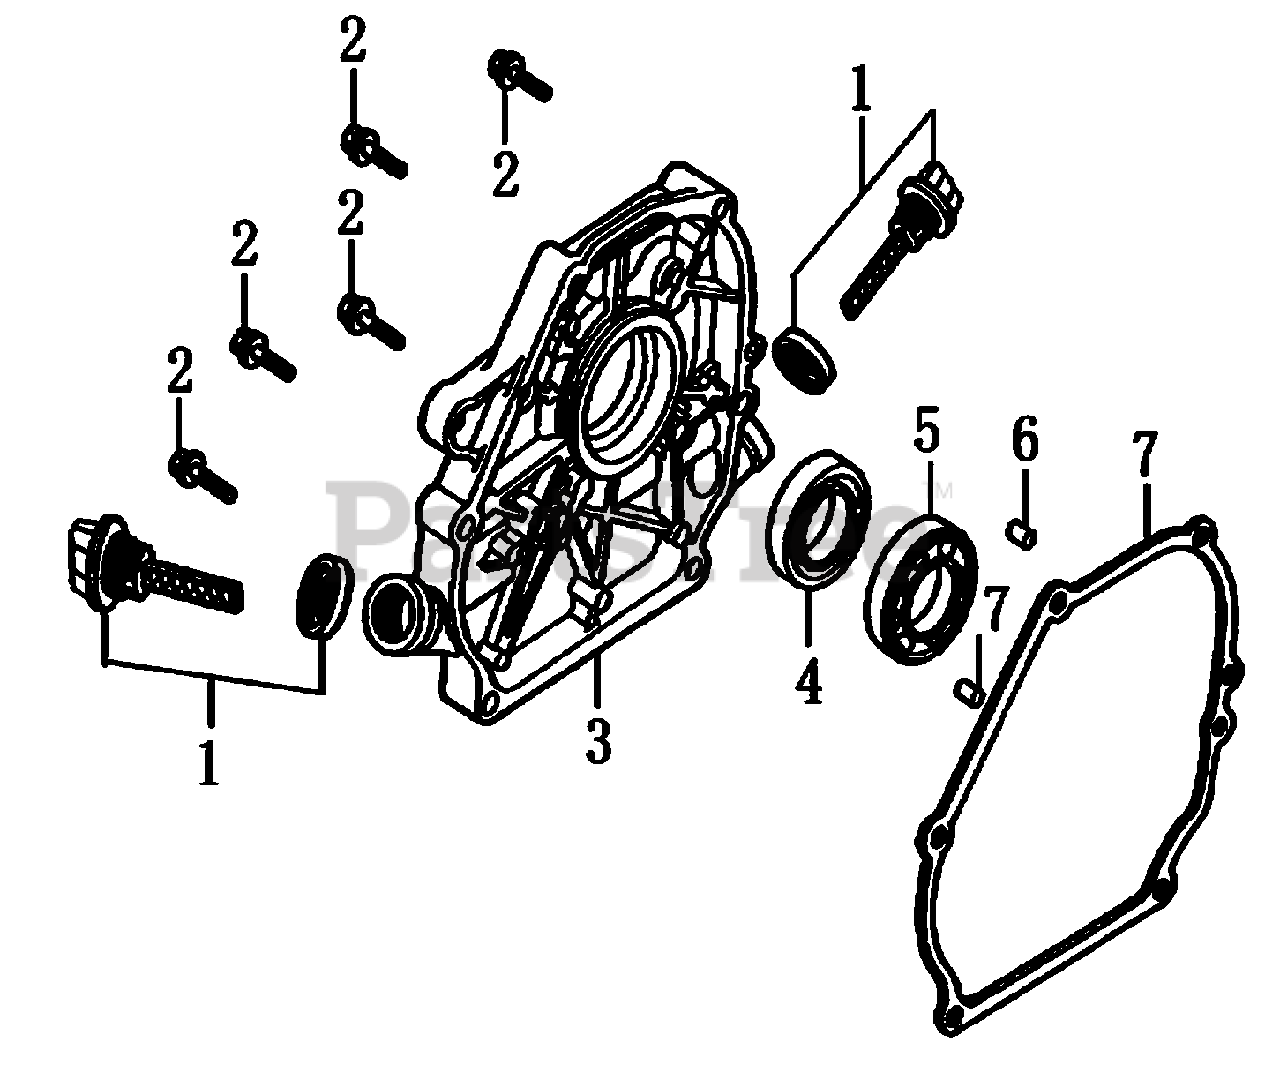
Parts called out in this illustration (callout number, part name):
1	CAP ASSY. DIP STICK
2	BOLT, FLANGE
3	CASE COVER
4	OIL SEAL 25X41.25X6
5	BEARING, RADIAL BALL
6	PIN, DOWEL
7	GASKET, CRANK CASE COVER
